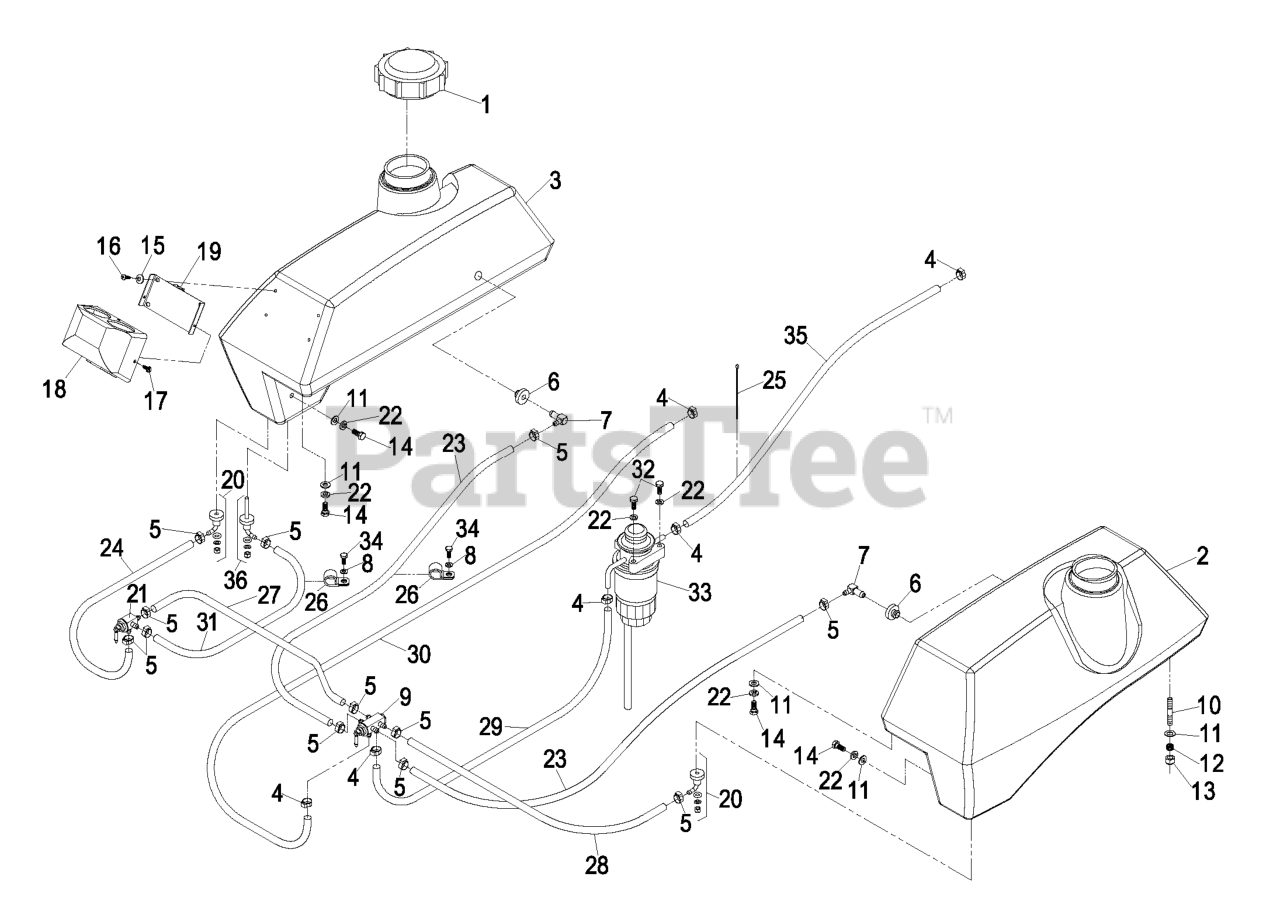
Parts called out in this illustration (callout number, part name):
2	KIT, FUEL TANK LH XP DD
3	KIT, FUEL TANK RH XP DD
4	CLAMP-HOSE, FUEL
5	CLAMP-HOSE, FUEL
7	ELBOW-90 DEG
8	WASHER-LOCK
9	VALVE-FUEL, DUAL FLOW
10	STUD
11	WASHER-PLAIN
12	SPRING-TANK, FUEL
13	NUT-LOCK, NI
14	SCREW-HH
15	WASHER-SPRING
16	SCREW-PPH
18	COVER,GAUGES
19	BRACKET,GAUGE MOUNT
20	FITTING-FUEL, BULKHEAD
21	VALVE,FUEL DIVERTER 90 DE
22	WASHER-LOCK
24	HOSE-FUEL
25	TIE-PLASTIC
26	CLIP-LOOM
28	FUEL LINE,19.0
29	HOSE-FUEL
30	HOSE-OVERFLOW
32	SCREW-HH
33	Briggs & Stratton P/N 820311 Fuel Filter
34	SCREW-HH
36	FTG, FUEL BULKHEAD LONG
